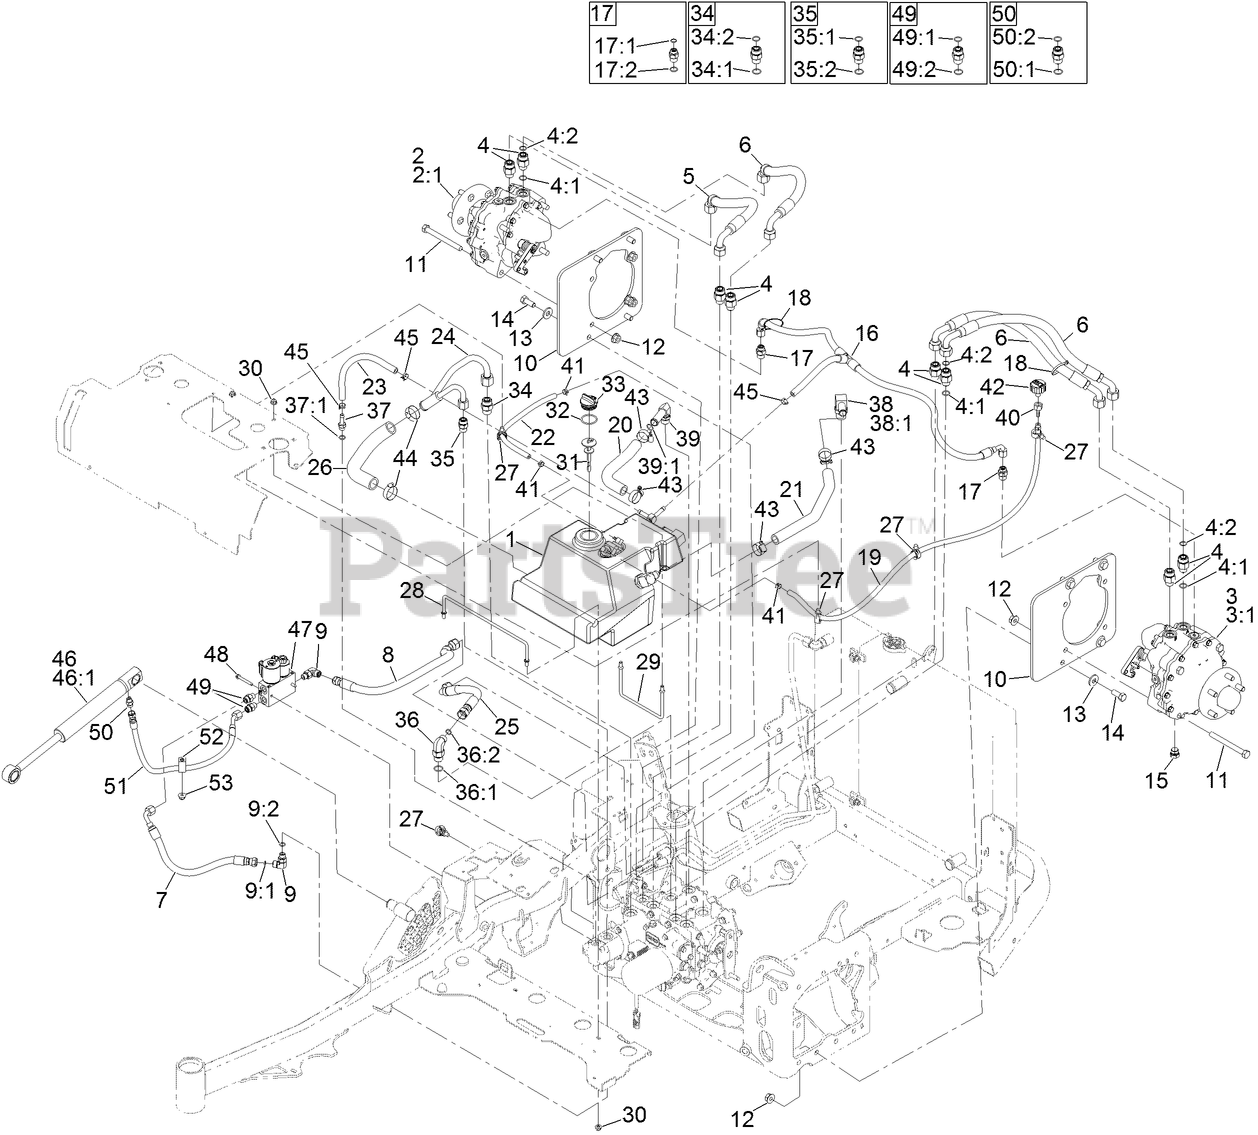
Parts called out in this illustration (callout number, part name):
1	HYD RESERVOIR ASM
2	MOTOR-HYD, RH
2:1	5 STUD WHEEL HUB KIT
3	MOTOR-HYD, LH
3:1	5 STUD WHEEL HUB KIT
4	FITTING-STRAIGHT
4:1	O-RING
4:2	O-RING
5	HOSE ASM
6	HOSE ASM
7	HOSE ASM
8	HOSE ASM
9	FITTING-ELBOW, 90 DEG
9:1	O-RING
9:2	O-RING
10	PLATE-MOTOR
11	SCREW-HH
12	NUT-HHF
13	WASHER-SPRING
14	SCREW-HH
15	PLUG-MAGNETIC
16	TEE HOSE ASM
17	FITTING-STRAIGHT
17:1	O-RING
17:2	O-RING
18	TIE-CABLE
20	HOSE-RETURN
21	HOSE-RETURN
24	TUBE ASM
25	HOSE ASM
26	HOSE-SUCTION
27	CLIP-TIE
28	ROD-SUPPORT, HYD TANK
29	ROD-SUPPORT, HYD TANK
30	NUT-HF, NI
31	DIPSTICK
32	O-RING
33	PLUG-PLASTIC
34	FITTING-STRAIGHT
34:1	O-RING
34:2	O-RING
35	FITTING-STRAIGHT
35:1	O-RING
35:2	O-RING
36	FITTING-ELBOW, 90 DEG
36:1	O-RING
36:2	O-RING
37	ADAPTER-STRAIGHT
37:1	O-RING
38	FITTING-ELBOW, 90
38:1	O-RING
39	FITTING-90
39:1	O-RING
40	FITTING-STRAIGHT
41	CLAMP-HOSE
42	BREATHER
43	CLAMP-HOSE
44	CLAMP-HOSE
45	CLAMP-HOSE
46	CYLINDER-LIFT
46:1	KIT, CYL REPAIR
47	DECK LIFT VALVE ASM
48	SCREW-HWHTF
49	FITTING-STRAIGHT
49:1	O-RING
49:2	O-RING
50	FITTING-HYD, STRAIGHT
50:1	O-RING
50:2	O-RING
51	HOSE ASM
52	CLIP-LOOM
53	NUT-HF, NI
